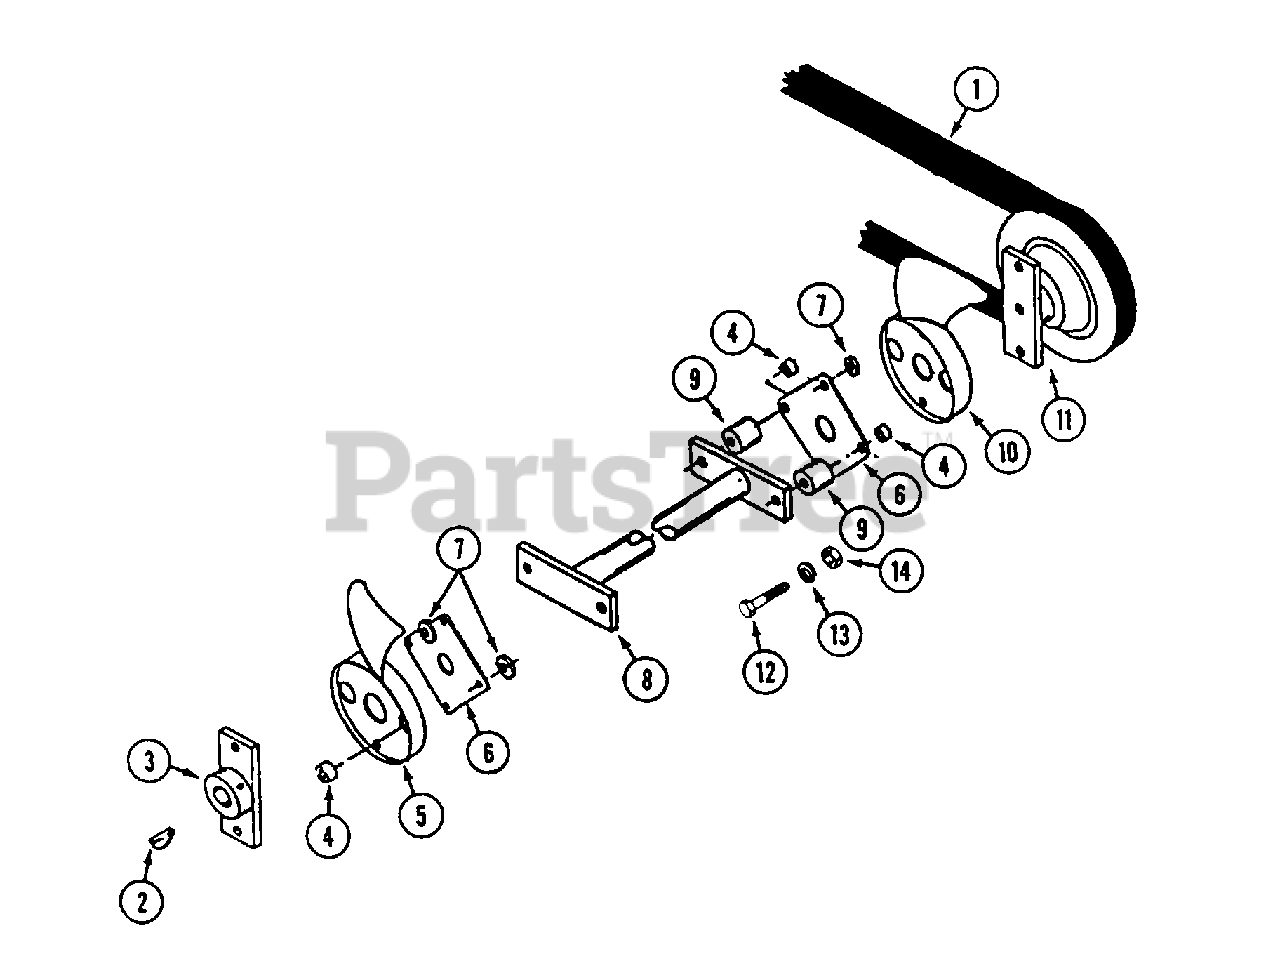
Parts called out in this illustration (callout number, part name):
1	BELT - transmission drive
2	KEY - woodruff 1/8" x 1/2"
3	HUB - drive plate
4	SPACER - bolt
7	WASHER - 1/4" 10 ga
8	SHAFT - cross
11	PULLEY - drive
12	BOLT - 5/16" - 18 x 2"
12	BOLT - 5/16" - 18 x 1-1/4"
12	BOLT - 5/16" - 18 x 1"
13	LOCKWASHER - 5/16"
14	NUT - 5/16" - 18
